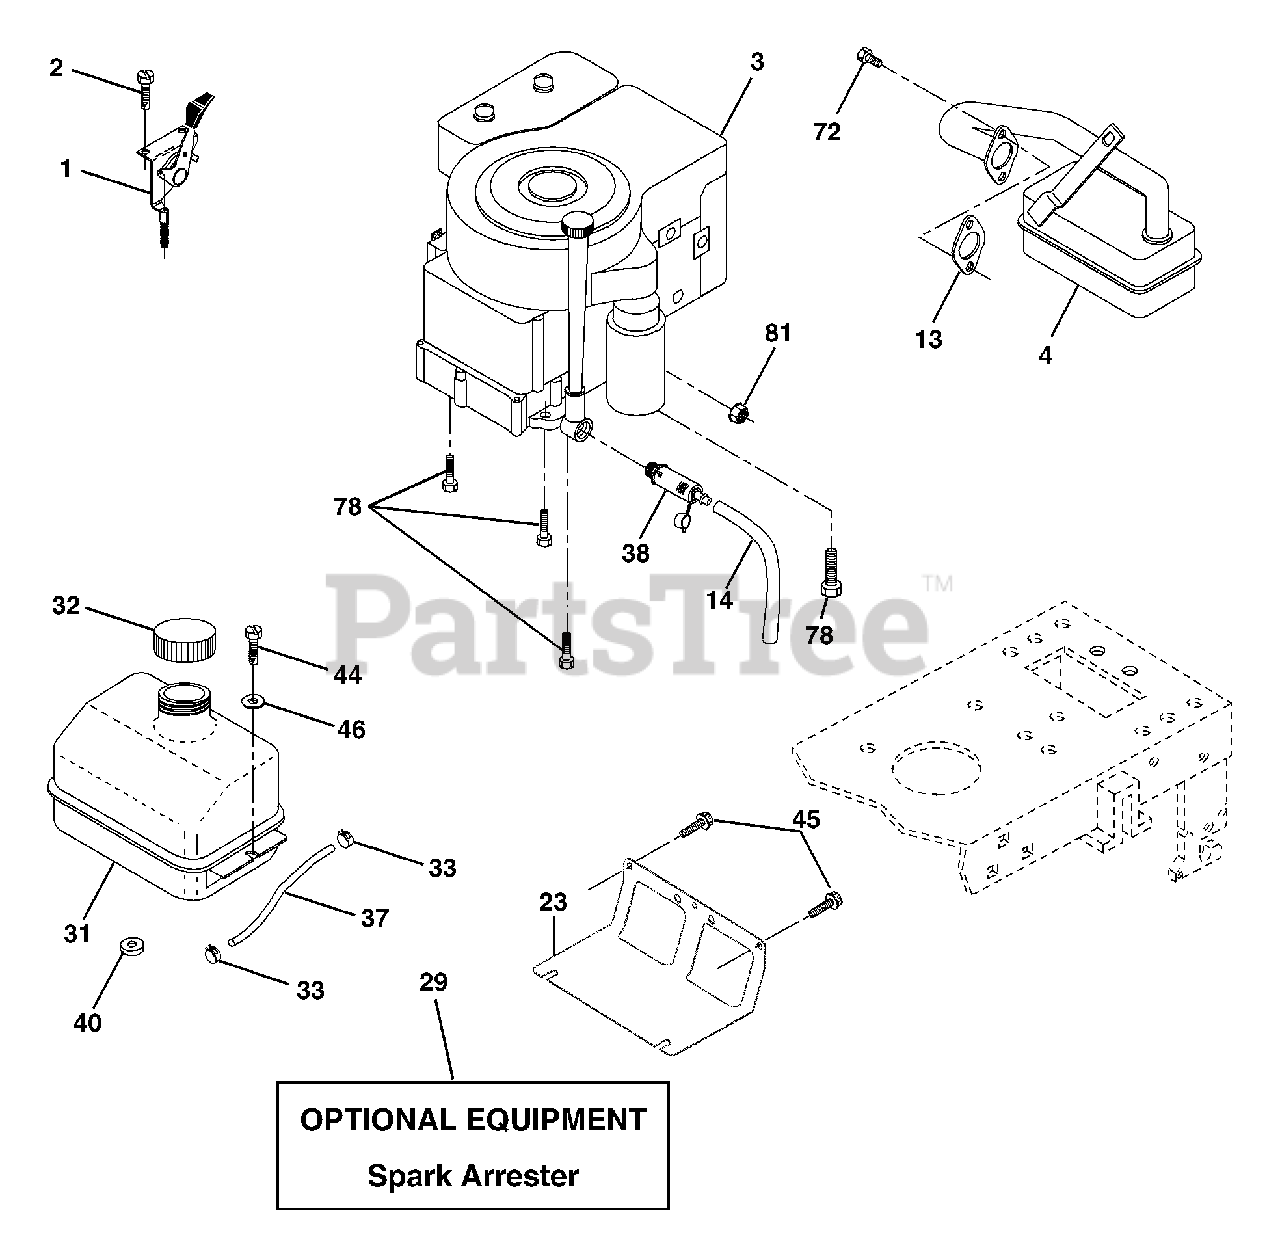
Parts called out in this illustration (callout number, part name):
1	Control Th/ch Flag
2	Screw Hex Thd Cut 1/4-20 x 1/2
4	Muffl er Exhaust B&S
13	Gasket Eng 1 313 Id Tin Plated
14	Tube Drain Oil Easy
23	Shield BRN/DBR Guard
29	Kit Spark Arrestor (Flat Scrn)
31	Tank Fuel Front
32	Cap Asm Fuel
33	Clamp Hose
37	Line Fuel 20"
38	Plug Drain Oil
40	Bushing Snap Nyl Blk Fuel Line
44	Screw Thdrol 1/4-20 x 3/4
45	Screw Hex Wsh Thdrol 3/8-16
46	Washer 9/32 x 7/8 x 16 Ga.
72	Screw Scocket Head 5/16-18 x 1
78	Screw 3/8-16 x 1-1/4
81	Nut Keps Hex 1/4-20 unc
